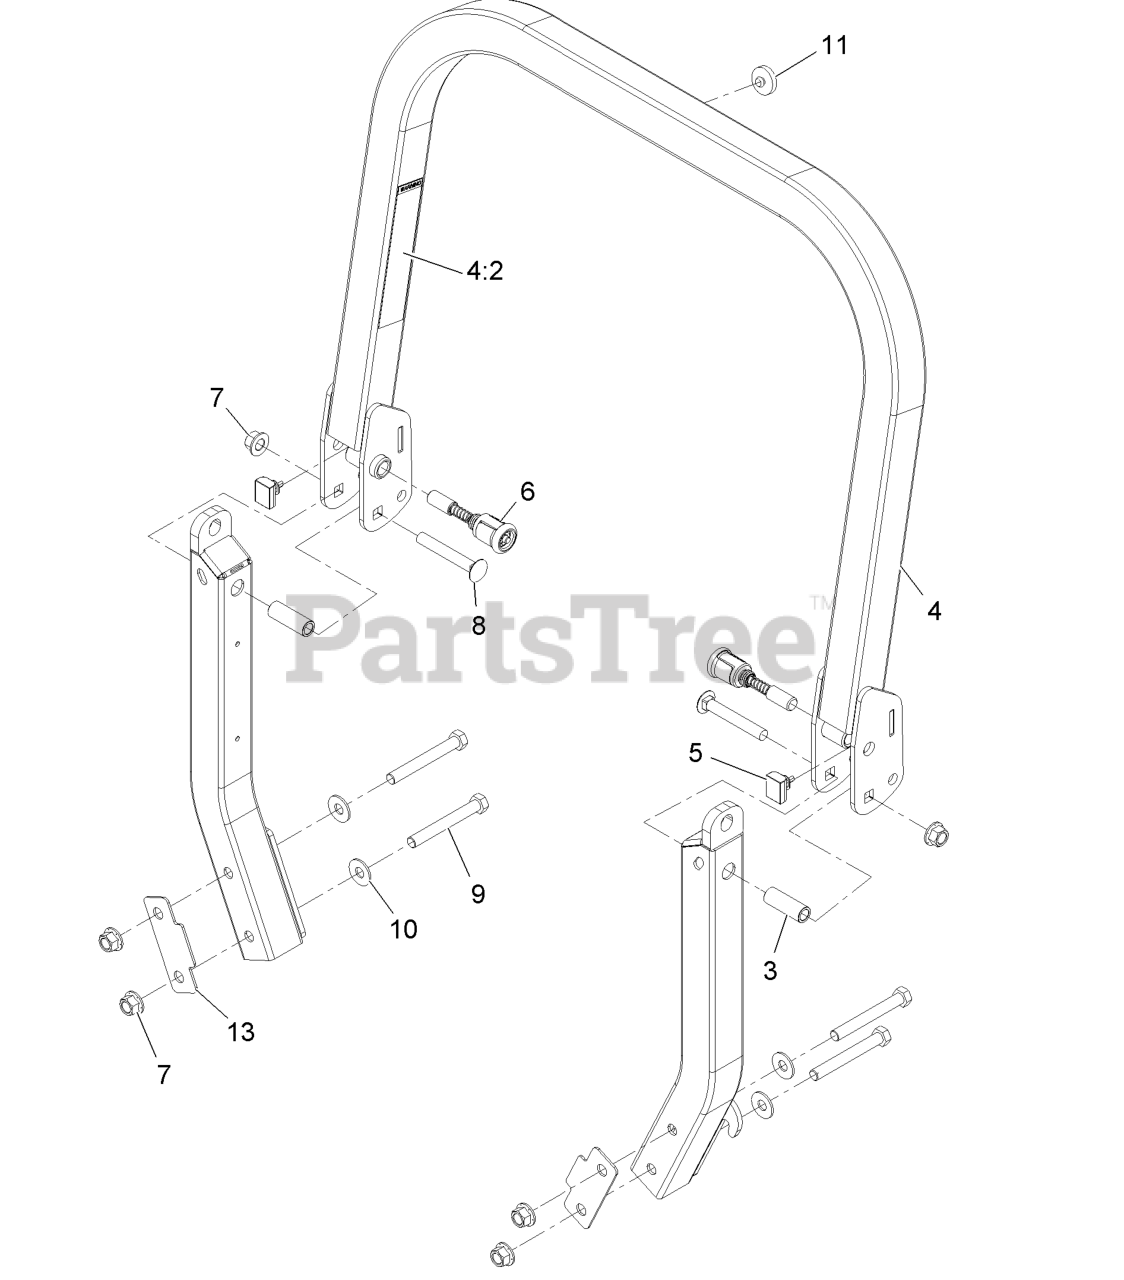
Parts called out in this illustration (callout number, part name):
4	UPPER ROPS ASM
4:2	DECAL-WARNING, FOLDING RO
5	BUMPER-ROPS
6	PIN-SPRING
7	Nut-Lock 1/2-13
8	SCREW-CARR
9	SCREW-HH
10	WASHER-SPRING
11	BUMPER-PUSH-IN, RUBBER
